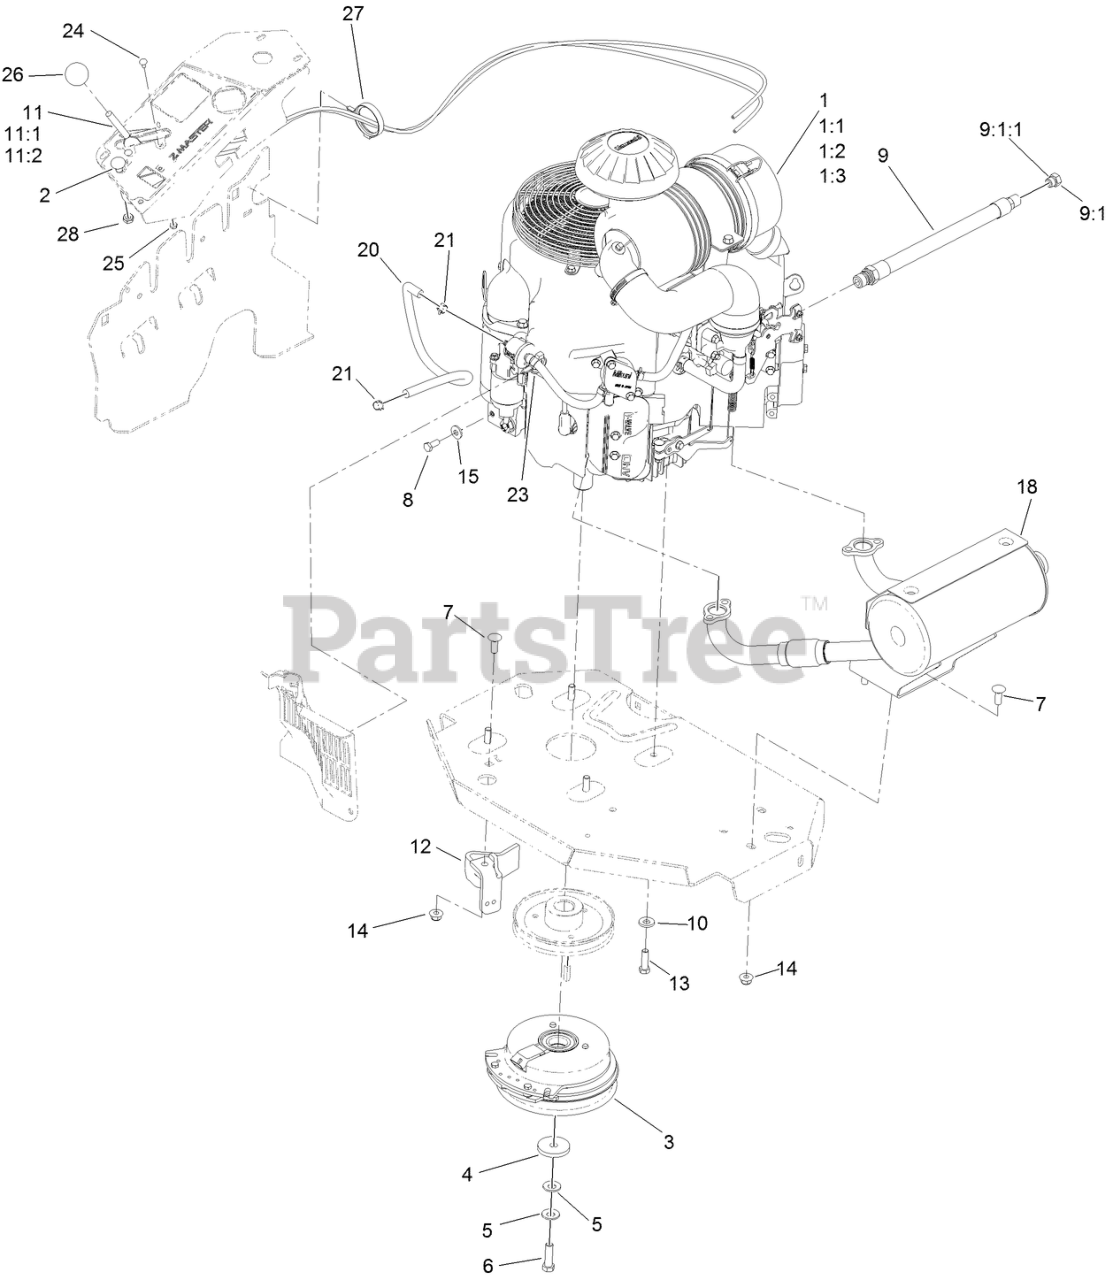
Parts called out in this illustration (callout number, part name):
1:1	KAWASAKI 49065-7010 ENGINE OIL FILTER
1:2	KAWASAKI 11013-7044 ENGINE AIR FILTER
1:3	KAWASAKI 11013-7045 SAFETY FILTER
2	CONTROL-CHOKE
3	CLUTCH KIT
4	WASHER-CLUTCH
5	WASHER-SPRING
6	SCREW-HH, W/LOCTITE
7	SCREW-CARR
8	SCREW-HH
9	ENGINE OIL DRAIN HOSE ASM
9:1	PLUG-HH
9:1:1	O-RING
10	WASHER-BELLEVILLE
11	THROTTLE CONTROL ASM
11:1	LEVER-THROTTLE
12	CLUTCH-ANCHOR
13	SCREW-HH
14	NUT-HF, NI
15	WASHER-SPRING
18	MUFFLER, FX850/801 FLEX
20	HOSE-FUEL
21	CLAMP-HOSE
23	CLAMP-HOSE
24	BOLT-CARR
25	NUT-LOCK, NI
26	KNOB-BALL
27	CLAMP-HARNESS
28	NUT-HJ
